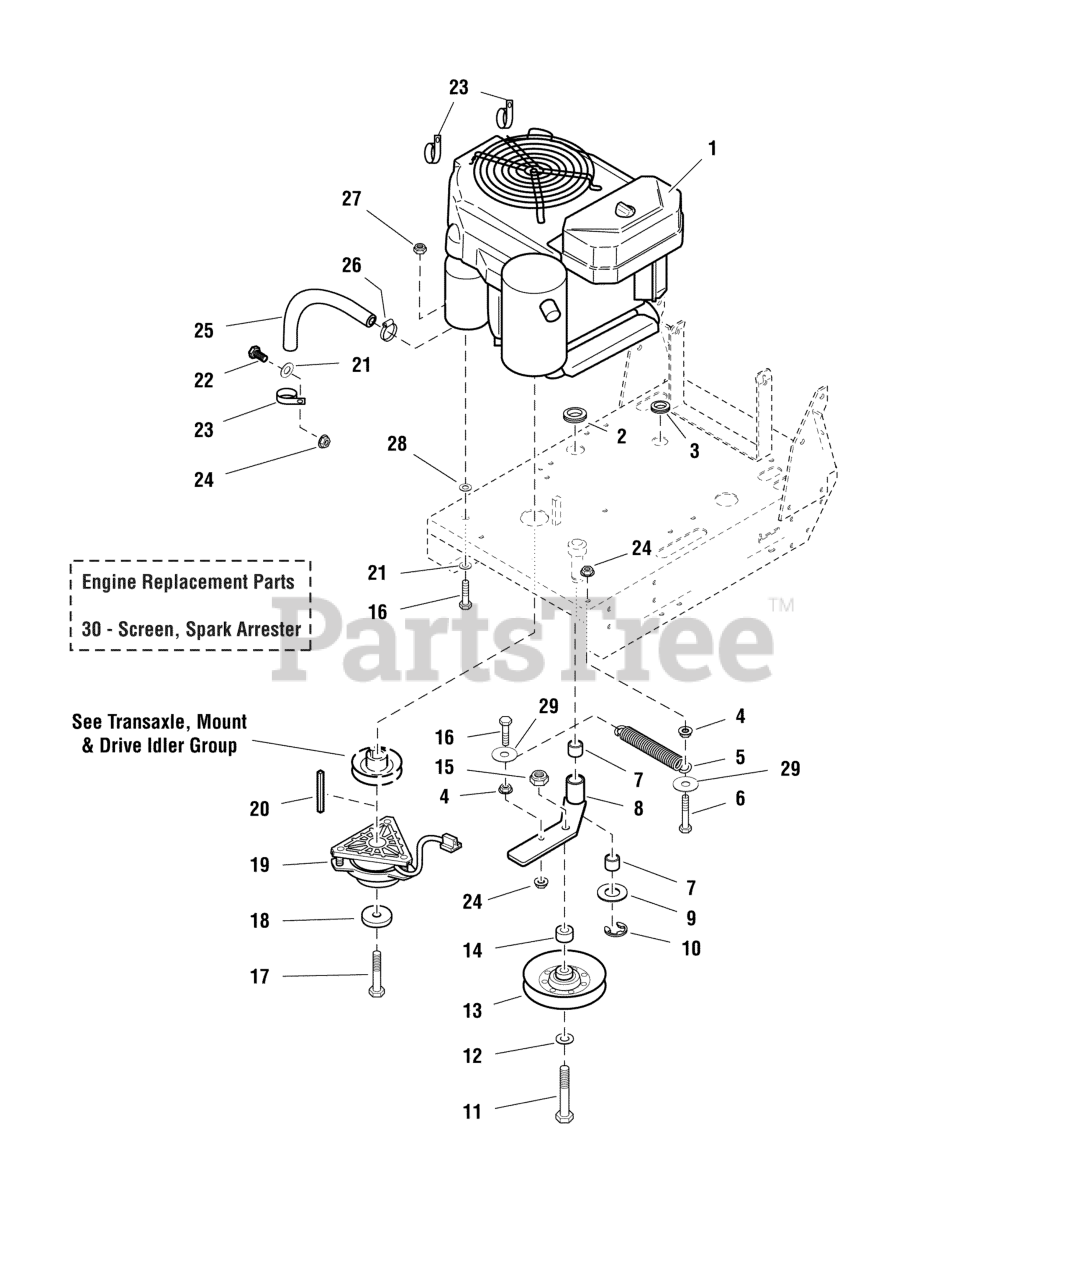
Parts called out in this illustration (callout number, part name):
1	ENGINE, 13HP KAI ELEC START
2	GROMMET, 7/8
3	GROMMET, 1/2
4	NUT, 5/16-18 HEX SERRATED FLANGE (LARGE)
5	SPRING, EXTENSION
6	BOLT, 5/16-18 X 2-1/4" GD5 YZ
7	BUSHING, BRASS, 3/4 X 1 X 1
8	WELD, IDLER ARM
9	WASHER, 3/4 SAE
10	C-CLIP, 3/4" SHAFT
11	BOLT, 1/2-13 X 2-3/4 GD5 CZ
12	WASHER, 1/2 SAE
13	PULLEY, IDLER, V-NOTCH, 5
14	SPACER, .52 X 1.00 X .38
15	NUT, 1/2-13 HEX NYLON LOCK
16	BOLT, 5/16-18 X 1-1/2" GD5 YZ
17	BOLT, CRANKSHAFT, 7/16"X2.75
18	SPACER, .45 X 1.62 X .37
19	CLUTCH, OGURA, 74 ft lbs - 1"
20	KEY, 1/4 SQ X 2
21	WASHER, 5/16" SAE
22	BOLT, 5/16-18 X 3/4 GD5
23	CLAMP, HOSE, 1.000 DIA.
24	NUT, 5/16-18 HEX NYLOCK FLANGE
25	HOSE, 1/2" PUSH-ON, 10.50"
26	CLAMP, #6 HOSE, STAINLESS
27	NUT, 5/16-18 HEX NYLON LOCK
28	WASHER, 5/16" INT. TOOTH LOCK
29	WASHER, 5/16" USS
30	SCREEN, SPARK ARRESTER-KAWI 13, 17, 19HP
